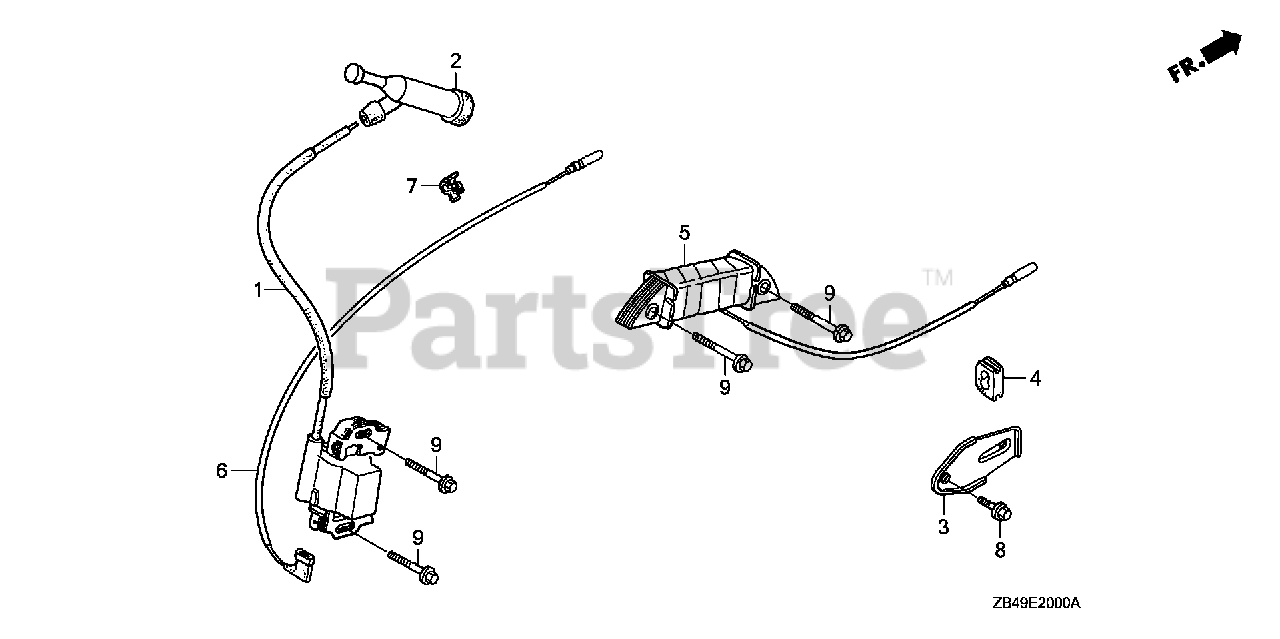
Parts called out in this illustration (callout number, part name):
1	COIL ASSY., IGNITION
2	CAP ASSY., NOISE SUPPRESSOR (NICHIWA Y-EZ RTFM256)
2	CAP ASSY., NOISE SUPPRESSOR (NGK Y-EZDB)
3	CLAMP, WIRE
4	GROMMET, WIRE
5	COIL ASSY., CHARGE (1A)
6	WIRE, STOP SWITCH (430MM)
8	BOLT, FLANGE (6X12) (CT200)
9	BOLT, FLANGE (6X28) (CT200)
